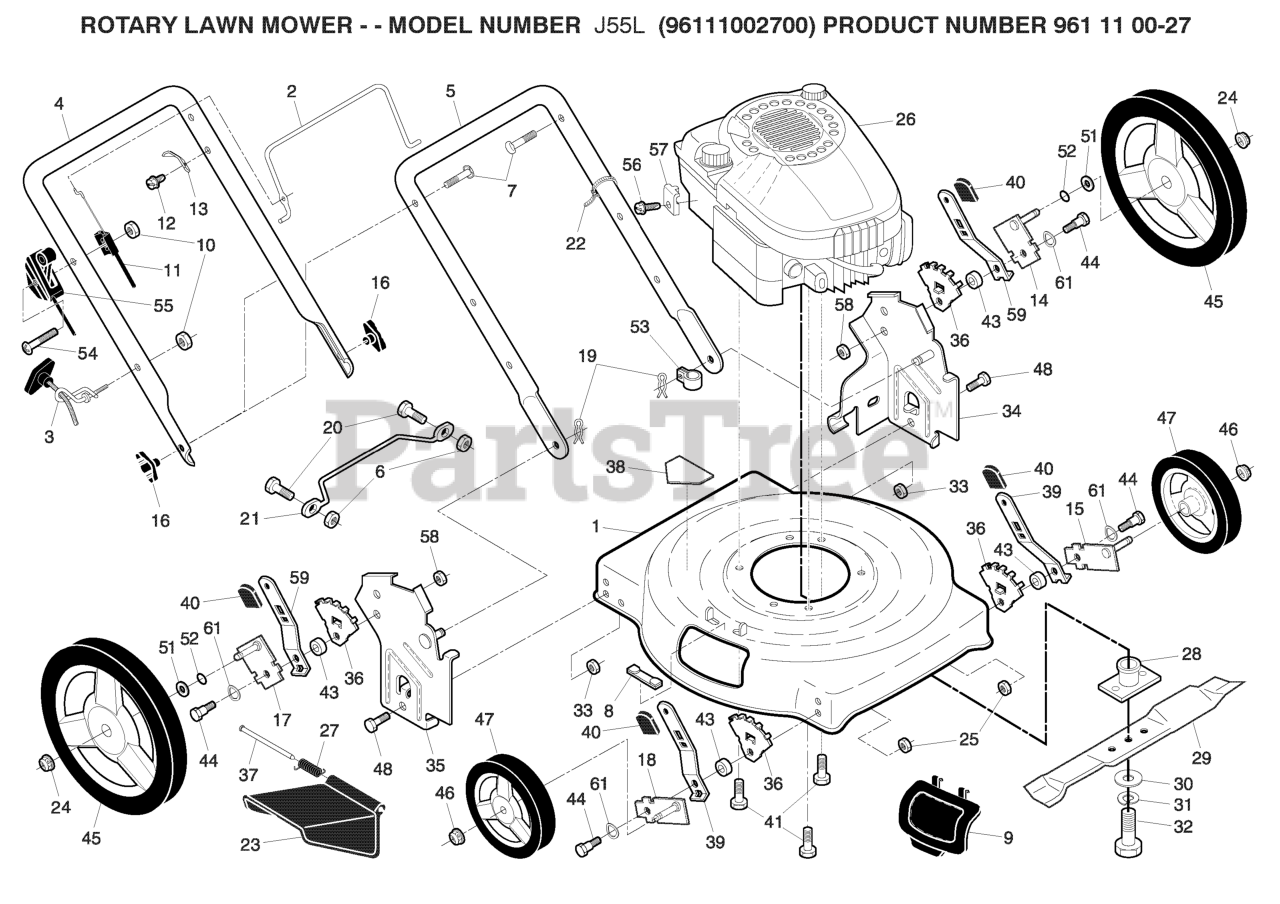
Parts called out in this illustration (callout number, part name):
1	Lawn Mower Housing
2	BAIL.MZR.STD.BLACK
3	RB GUIDE.ROPE.STD.BLK.ZIN WSL
4	Upper Handle
5	HANDLE.LOWER.GREY
7	BOLT, HANDLE 5/16-18X1.75
8	CLIP. CLOSEOUT
9	PLATE.MULCHER.22.ECON.BLACK
10	NUT
11	Engine Zone Control Cable
13	BRACKET UPSTOP
14	AXLE ARM ASSY REAR LH
15	AXLE ARM ASSY FRONT LH
16	KNOB, DEFLECTOR
17	AXLE ARM ASSY REAR RH
18	AXLE ARM ASSY FRONT RH
19	HAIRPIN COTTER
20	REPL BY 817 02 10-08
22	TIE GUIDE
23	GUARD.DISCHARGE.22".
24	NUT.HEX.FLANGE.3/8-16.LOCKNUT
25	LOCKNUT 5/16-18
27	SPRING.HINGE
28	ADAPTER.BLADE
29	Blade, 22"
30	WASHER,HARDEN
31	LOCKWASHER
32	SCREW, HEX HD 3/8-24 X 1-3/8
33	NUT.CENTERLOCK.5/16-
34	BRACKET.ASM.HANDLE.HW.
35	BRACKET.ASM.HANDLE.HW.RT.ORANG
36	WHEEL ADJ BRACKET FRONT
38	DECAL.INTERNATIONL.CUTFINGER
39	SELECTOR SPRING, FRONT
41	BOLT 3/8-16X1-1/8
43	SPACER.HEIGHT.ADJUSTER
44	SHOULDER BOLT 5/16-18
45	RP.WHEEL.12X1.75H 3 SPOKE.RAD
46	NUT.HEX.FLANGE.3/8-16.LO(3 2)
47	WHEEL AND TIRE ASSY, REAR
48	BOLT
51	O-RING..070X.487.NEOPRENE
52	WASHER.FLAT.1/2
53	CLIP.CABLE.BLK
55	THROTTLE CONTROL
56	SCREW.HEX.HEAD.WASHER.10-16
57	CABLE CLAMP(ENGINE)
58	NUT.LOCK.5/16-18
59	SPRING.SEL.EXT.21.DOMED.12/14
61	WASHER.CURVED.CYLINDRICAL
